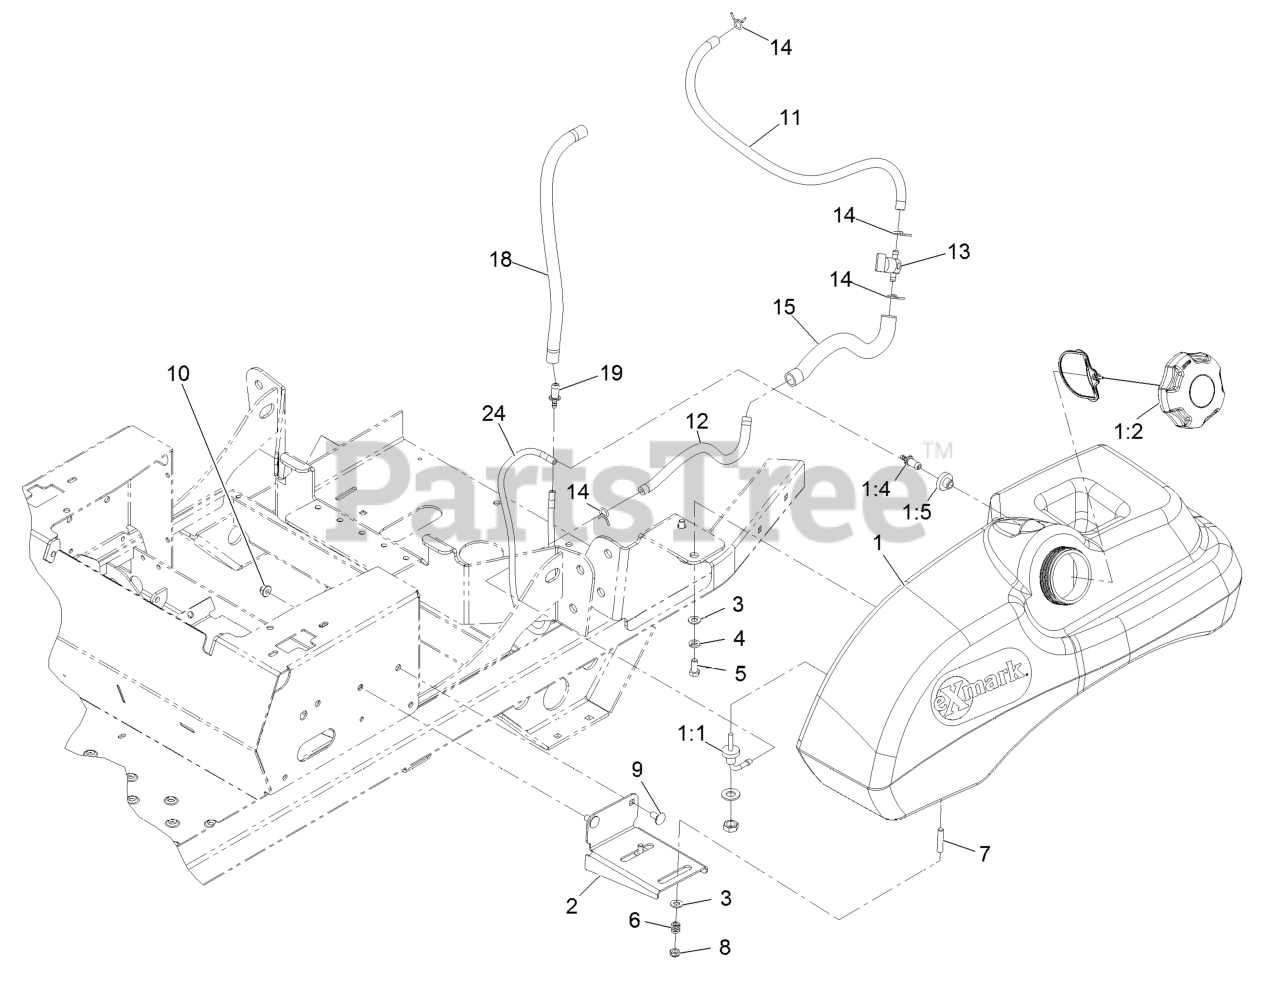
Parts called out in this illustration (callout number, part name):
1	ASM-FUEL TANK
1:1	FITTING-FUEL, BULKHEAD
1:4	FITTING-ORIFICE, STRAIGHT
1:5	BUSHING
2	BRACKET-TANK AND FENDER
3	WASHER-PLAIN
4	WASHER-LOCK
5	SCREW-HH
6	SPRING-TANK, FUEL
7	STUD
8	NUT-LOCK, NI
9	SCREW-CARR
10	NUT-HF, NI
11	HOSE-FUEL
12	HOSE-FUEL
13	VALVE-FUEL
15	CONDUIT-FUEL LINE
18	HOSE-FUEL
19	FITTING-ORIFICE, STRAIGHT
24	HOSE,EMISSIONS
